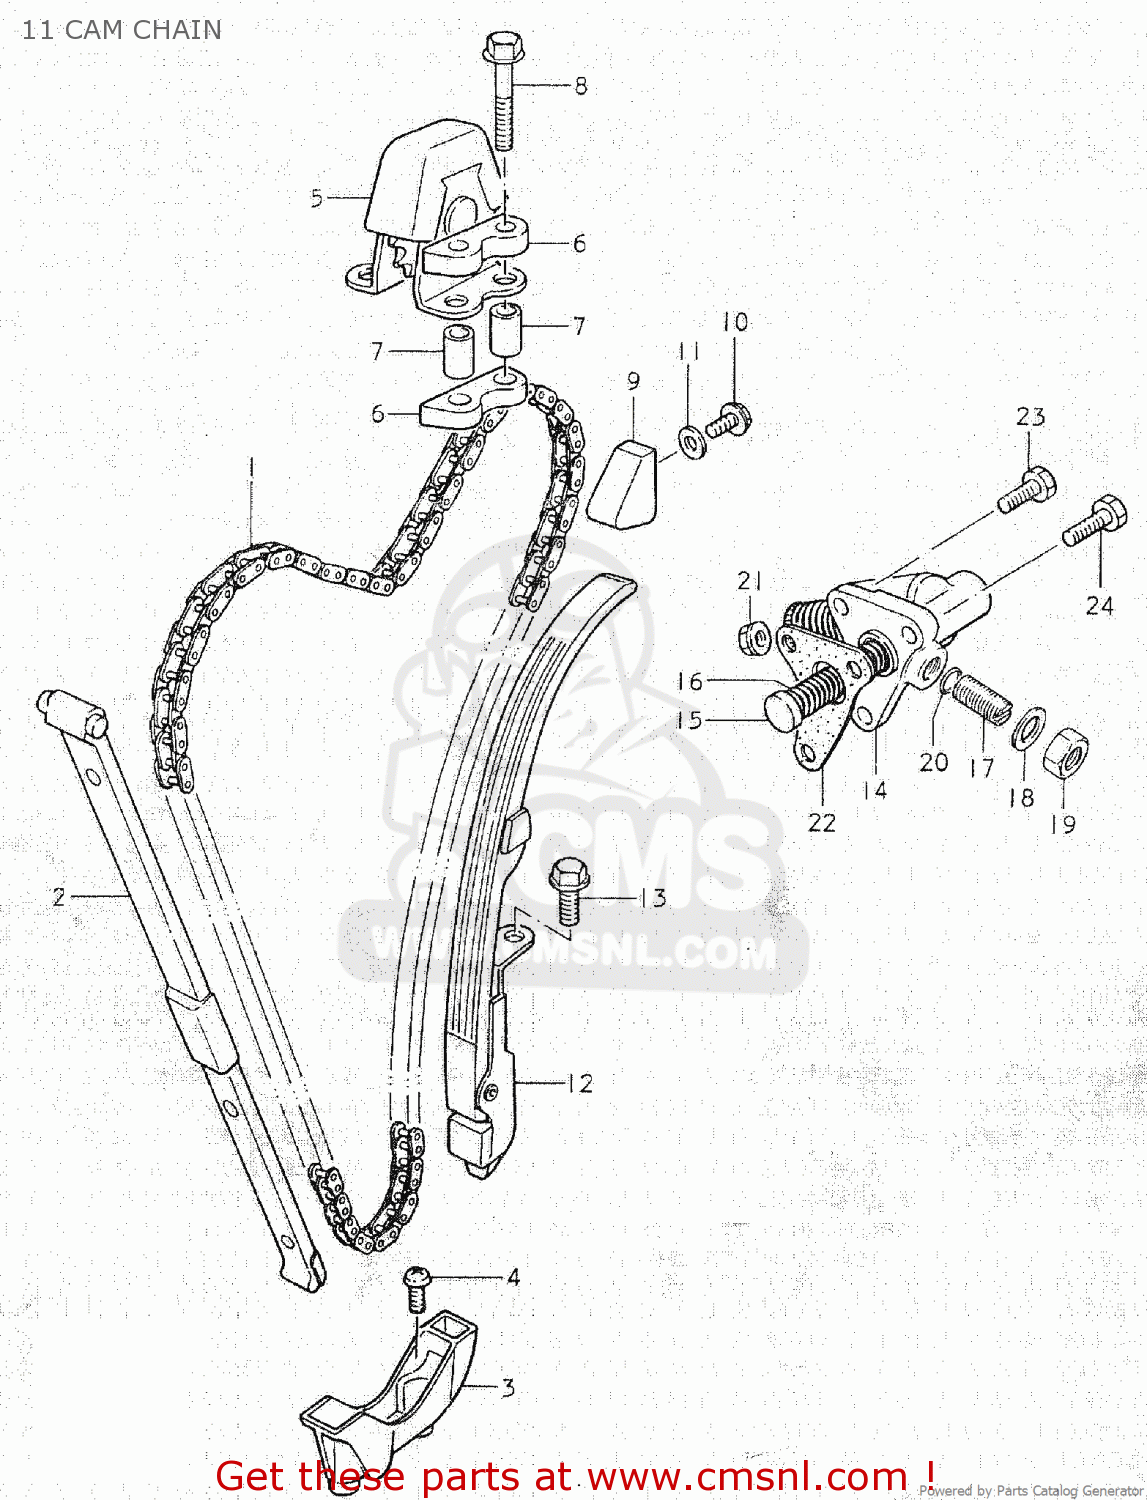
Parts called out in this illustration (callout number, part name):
1	CHAIN,CAMSHAFT DRIVE(120L)
2	GUIDE,CAM CHAIN
3	HOLDER,CAM CHAIN GUIDE
4	SCREW
5	IDLER,CAM CHAIN
6	CUSHION,IDLER
7	SPACER
8	BOLT
9	GUIDE,CAM CHAIN
10	BOLT
11	GASKET (NAS)
12	TENSIONER,CAM CHAIN
13	BOLT
14	ADJUSTER ASSEMBLY,TENSIONER
15	ROD,PUSH
16	SPRING
17	SCREW
18	WASHER
19	NUT
20	O-RING
21	NUT
22	GASKET,TENSIONER ADJUSTER (MCA)
23	SCREW
24	SCREW
